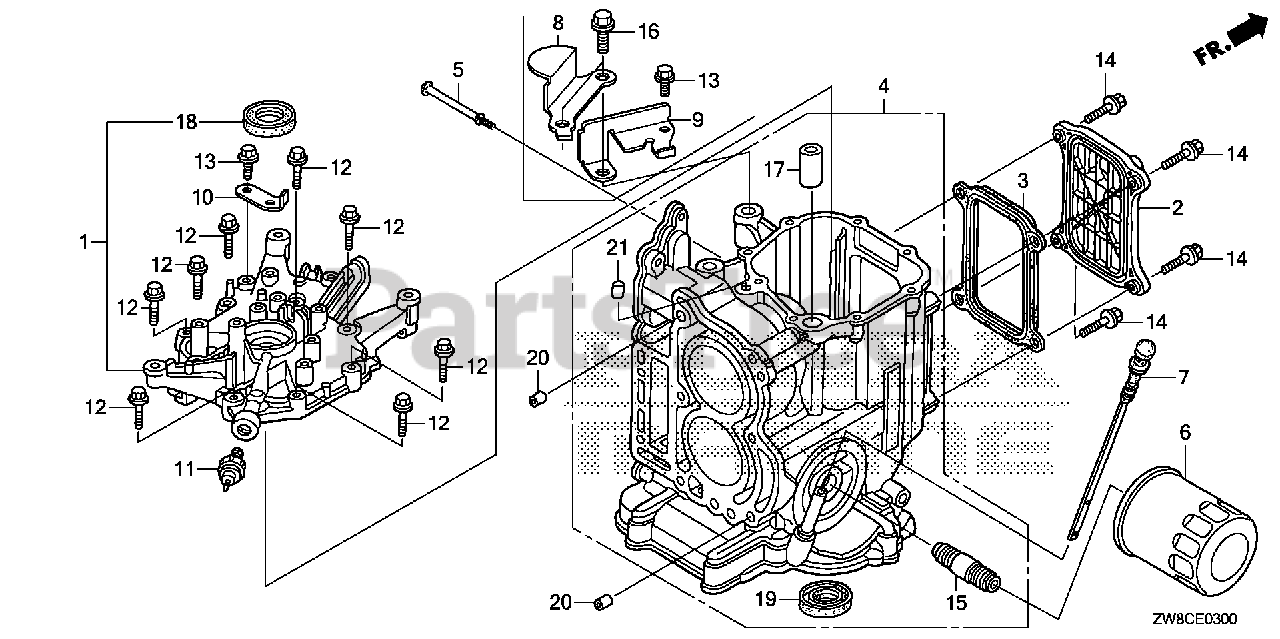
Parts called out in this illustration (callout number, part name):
1	COVER ASSY., CRANKCASE (000)
2	COVER, CRANKCASE SIDE
3	GASKET, CRANKCASE SIDE COVER
4	BLOCK ASSY., CYLINDER (000) *NH8* (DARK GRAY)
5	STOPPER, ENGINE SIDE
6	FILTER, OIL (TOYO ROKI)
6	FILTER, OIL (DENSO)
7	DIPSTICK, OIL
8	PLATE A, FLYWHEEL COVER
9	PLATE B, FLYWHEEL COVER
11	SWITCH ASSY., OIL PRESSURE
12	BOLT, FLANGE (6X28)
13	BOLT, FLANGE (6X14) (CT200)
14	BOLT, FLANGE (6X22) (CT200)
15	HOLDER, OIL FILTER
16	BOLT, FLANGE (8X25)
17	PIN, DOWEL (14X20)
18	OIL SEAL (30X42X7)
19	OIL SEAL (26X45X7)
20	PIN, DOWEL (10X12)
21	PIN B, DOWEL (8X14)
